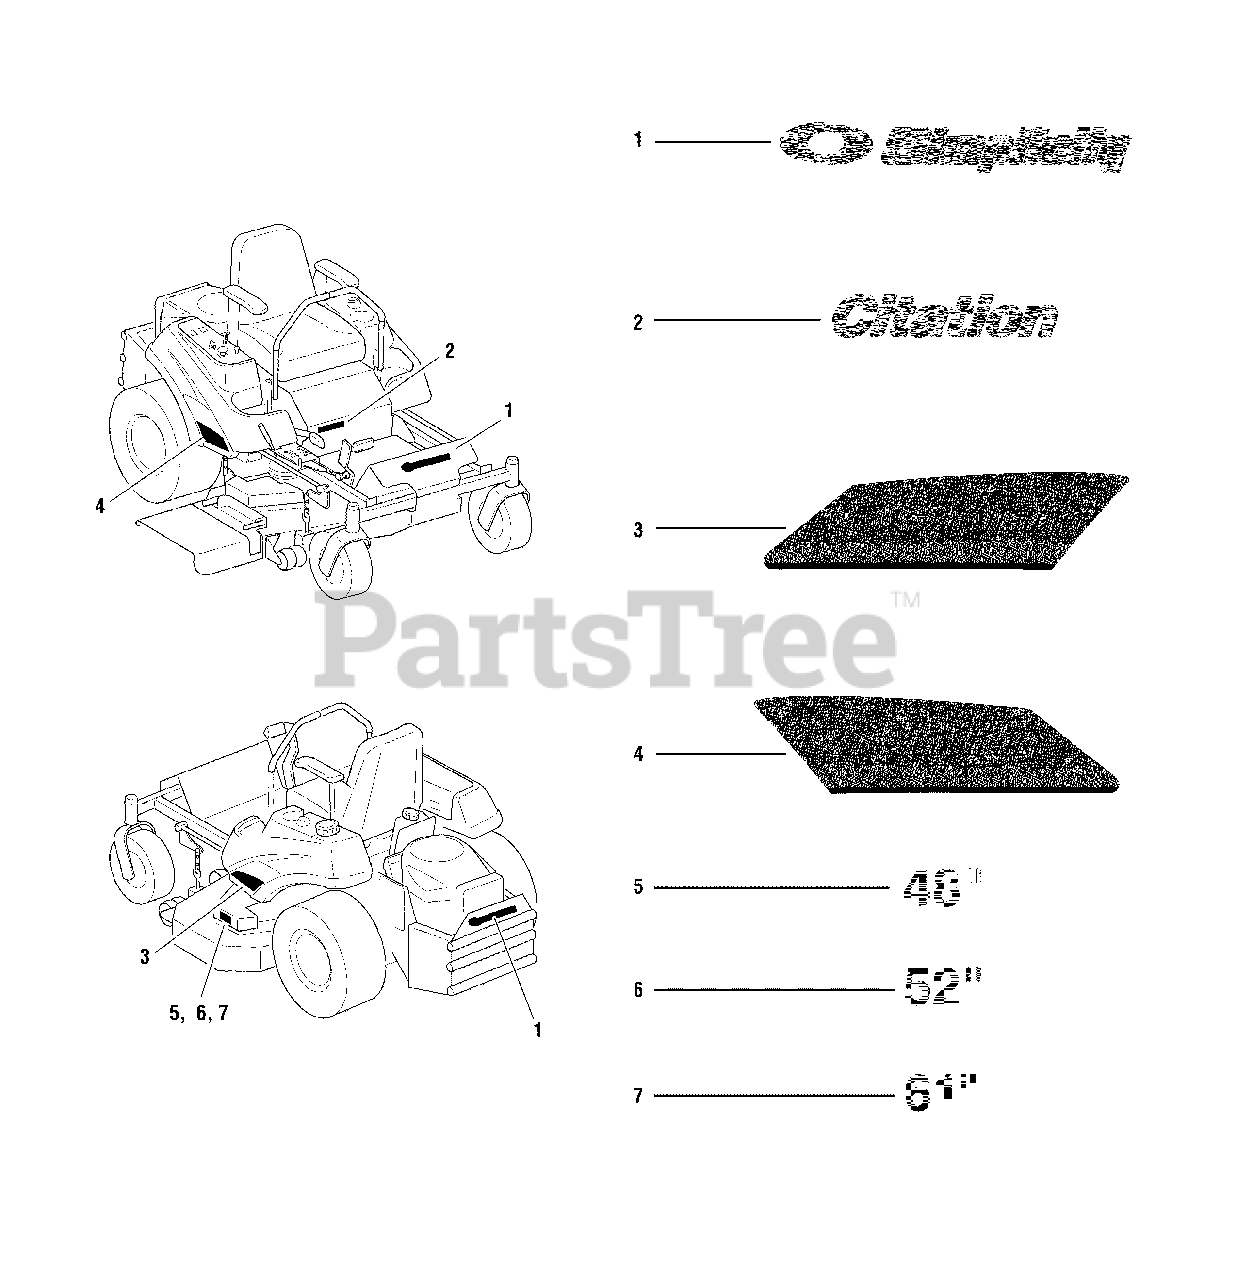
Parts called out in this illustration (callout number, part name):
1	DECAL, Simplicity Logo
2	DECAL, Citation
3	DECAL, Badge, RH
4	DECAL, Badge, LH
5	DECAL, 48"
6	DECAL, 52"
7	DECAL, 61"
